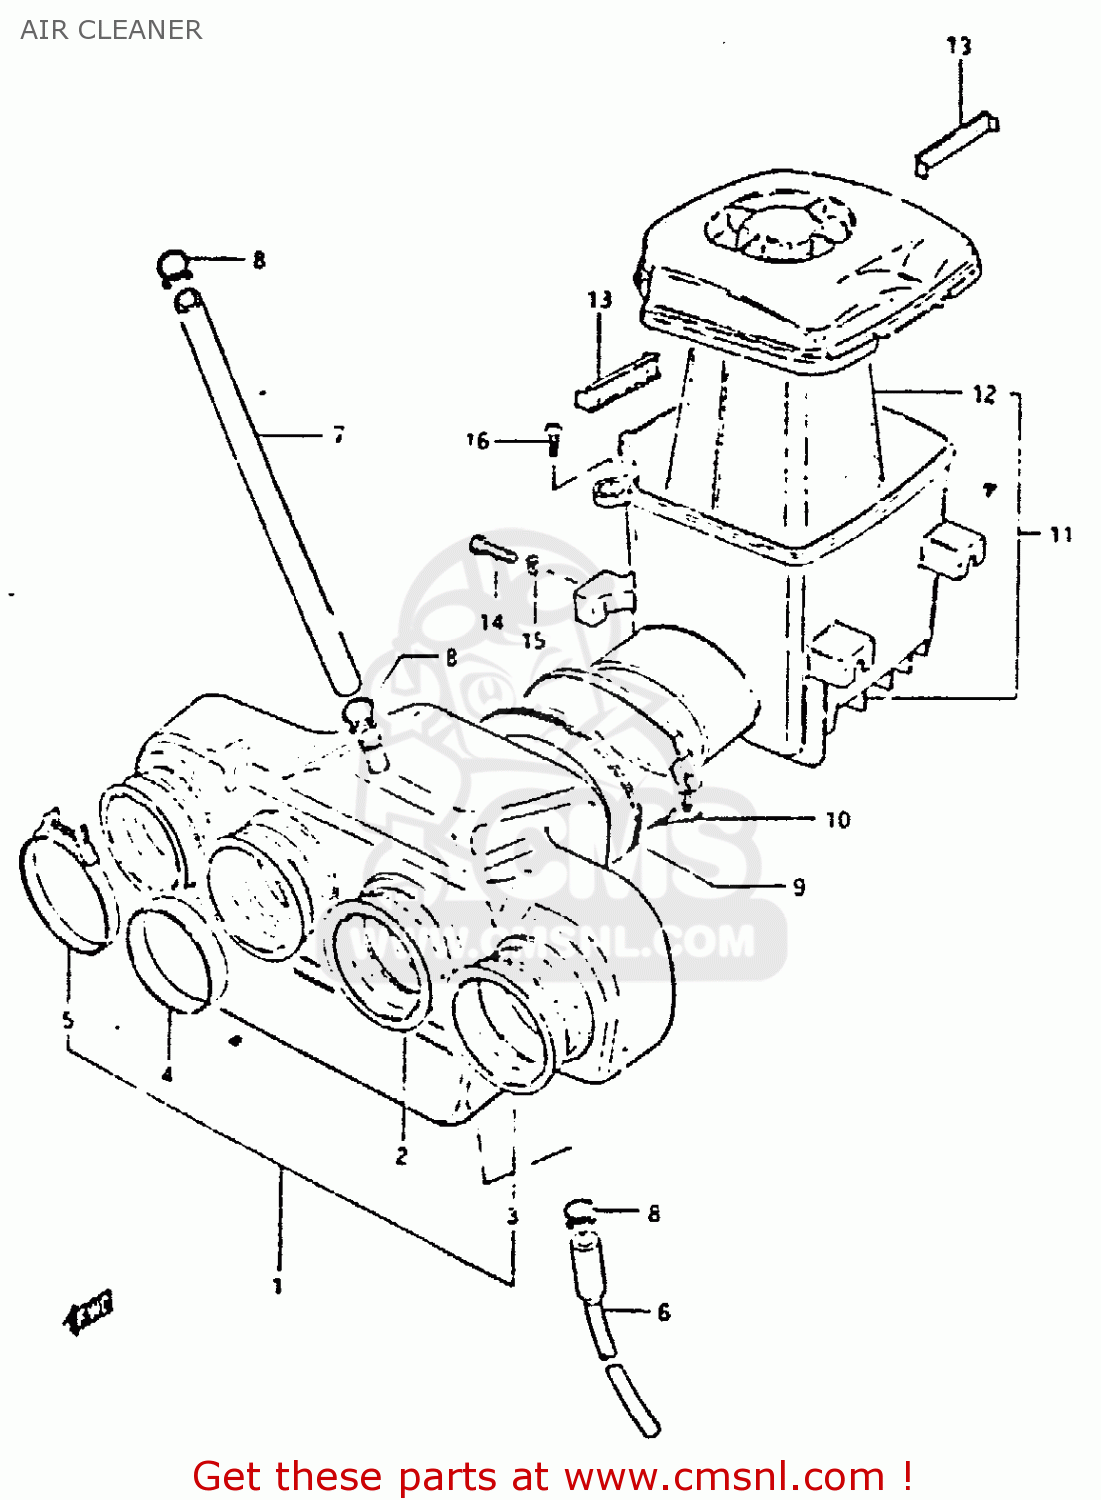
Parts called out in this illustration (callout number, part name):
1	CASE,AIR CLEANER,FRONT
2	TUBE,OUTLET,INNER
3	TUBE,OUTLET OUTER
4	RING,CARBURETOR AIR INLET HOSE
5	CLAMP
6	DRAIN TUBE
7	HOSE
8	CLIP
9	JOINT,HOSE AIR CLEANER
10	CLAMP
11	CLEANER SET,AIR,REAR
12	FILTER ASSY
13	SLIDER
14	BOLT, UPPER
15	LOCK WASHER
16	SCREW
